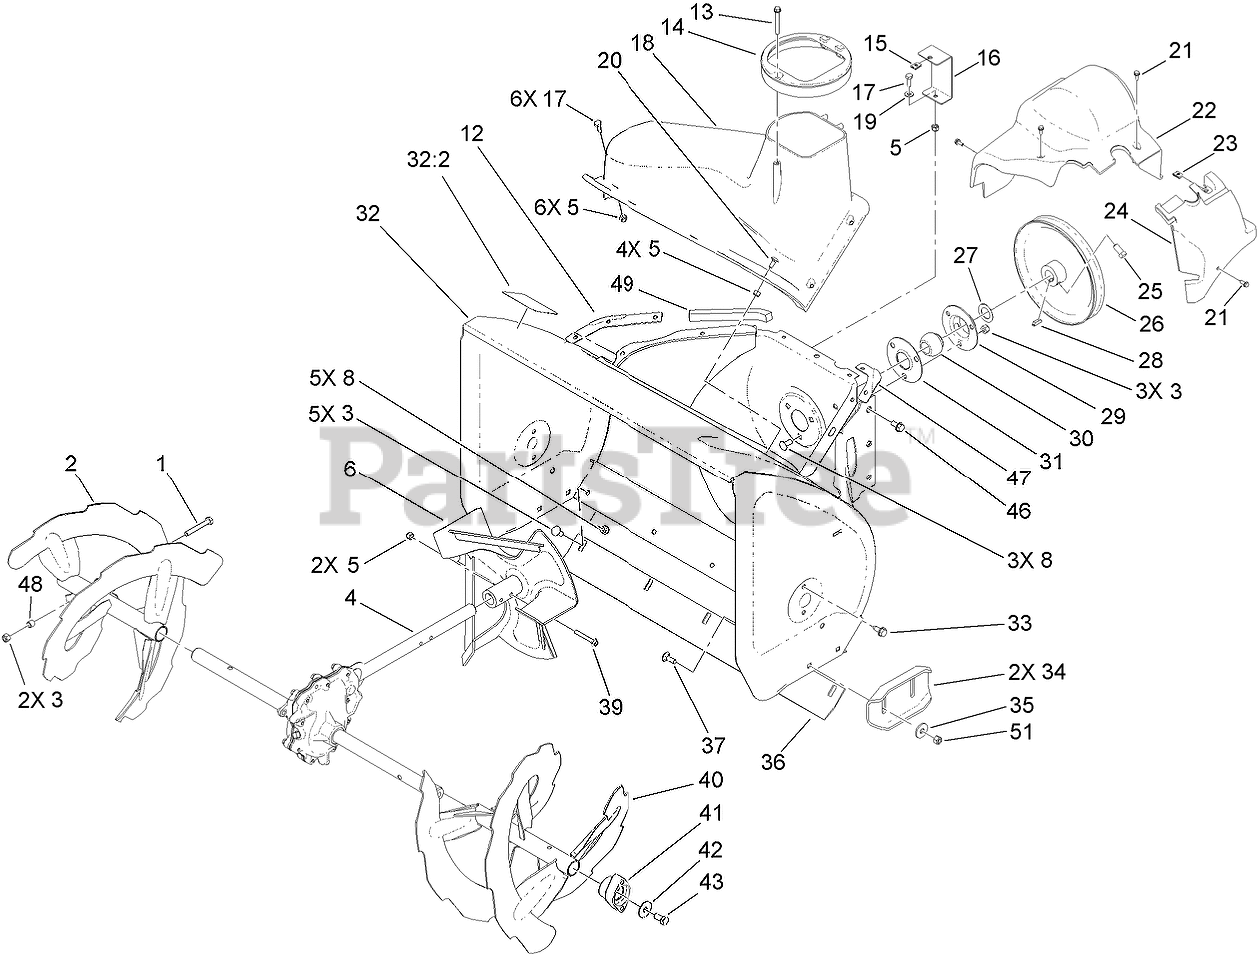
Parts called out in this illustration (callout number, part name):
1	SCREW-HH
2	RH AUGER ASM
3	NUT-LOCK, NI
4	26 INCH AUGER GEARCASE ASM
5	NUT-LOCK, NI
6	IMPELLER ASM
8	SCREW-CARR
12	SEAL-FLANGE, COVER
13	SCREW-PLASTITE
14	GUIDE-CHUTE
15	NUT-SPEED, U-TYPE
16	BRACKET-COVER, CLIP NUT
17	SCREW-HH
19	WASHER-FLAT
20	BOLT-CARR
21	SCREW-HWH
22	COVER-BELT
23	NUT-SPEED
24	COVER-EXTENSION, BELT
25	SCREW-SET, SQH
26	PULLEY-IMPELLER
27	WASHER-THRUST
28	KEY-WOODRUFF
29	FLANGE-CUP, BEARING
30	BEARING-BALL
31	FLANGE-CUP, BEARING
32	HOUSING-AUGER, 26 INCH
32:2	DECAL-DANGER, AUGER
33	SCREW-HWHTF
35	WASHER
36	SCRAPER-FIXED
37	SCREW-CARR
39	SCREW-HH
40	LH AUGER ASM
41	BEARING-AUGER
42	WASHER
43	SCREW-HH
46	SCREW-HWHTF
48	SPACER
49	SEAL-HOUSING
51	NUT-HF, NI
